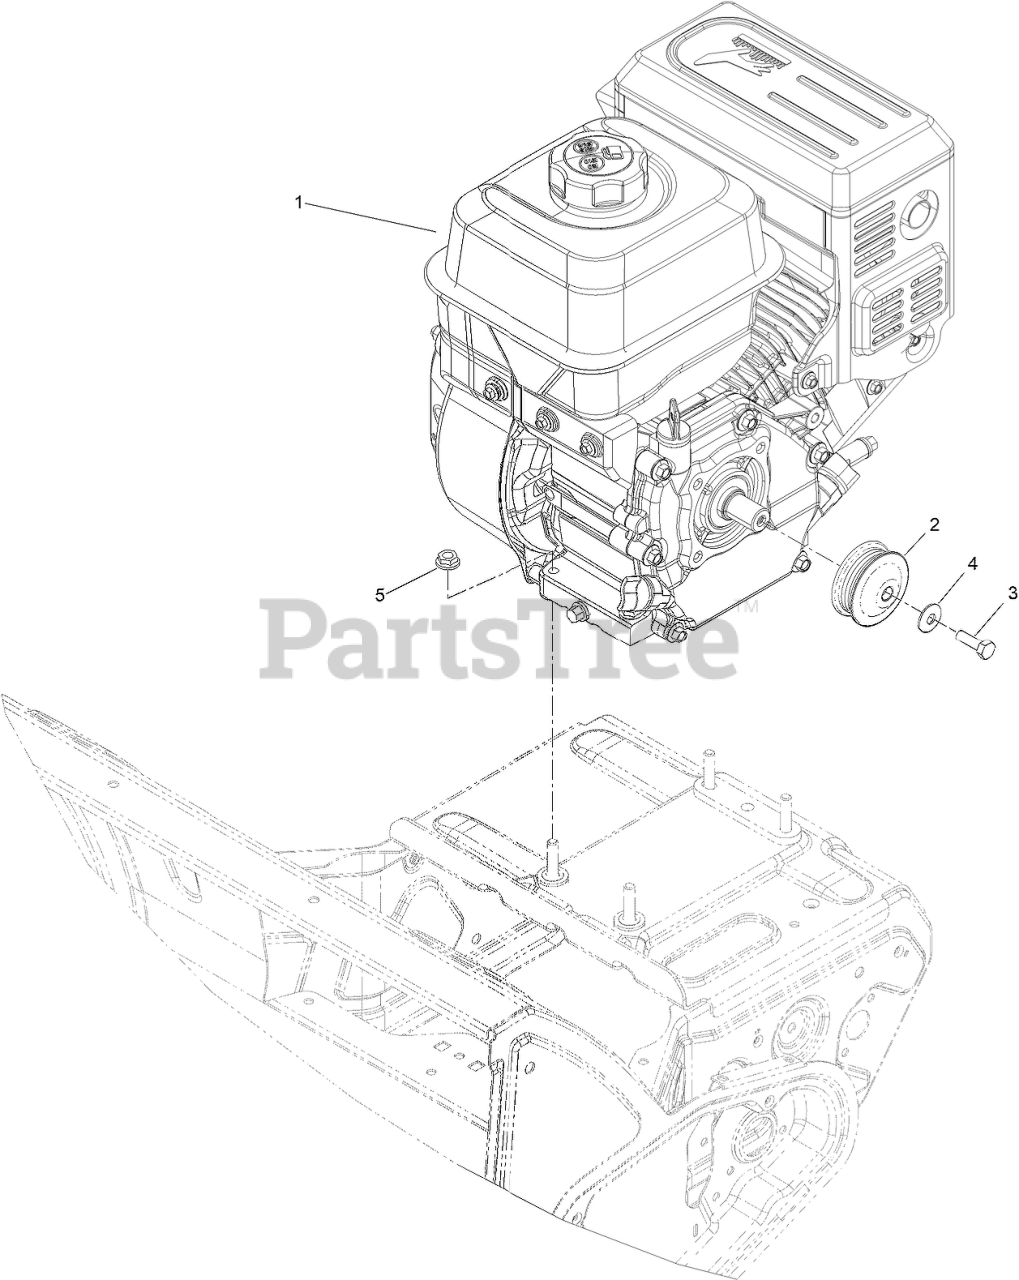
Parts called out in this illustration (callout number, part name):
1	ENGINE-G210FS-2
2	PULLEY-ENGINE
3	SCREW-HH, LOCK
4	WASHER-BELLEVILLE
5	NUT-HF
